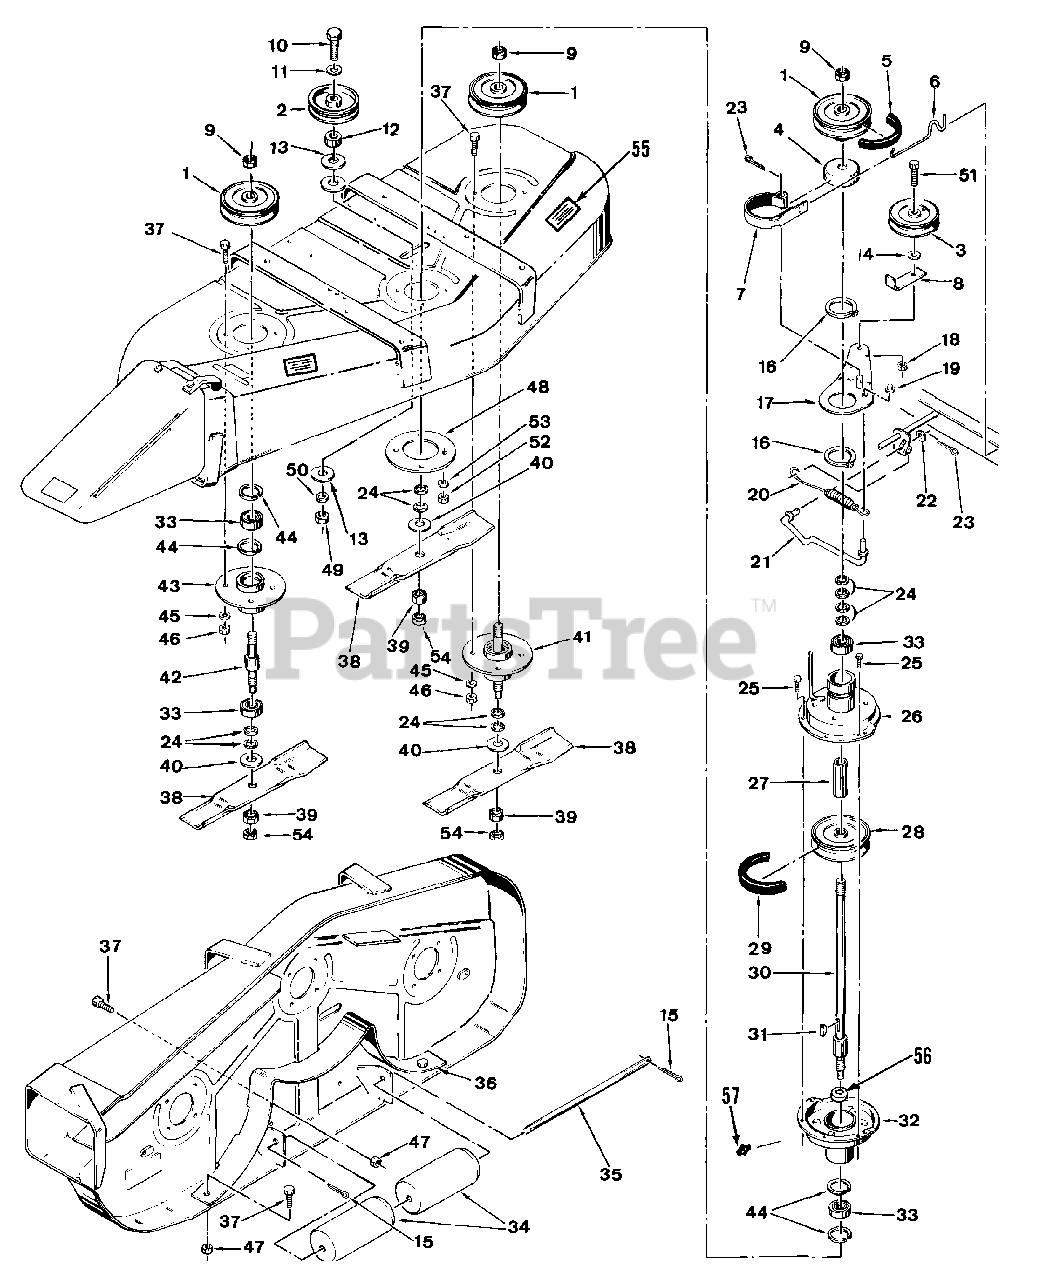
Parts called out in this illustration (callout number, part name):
1	Pulley
2	Pulley Deck Idler
3	Pulley - Idler
4	Brake Drum
5	Drive Belt
6	Brake Link
7	Brake Band
8	Belt Restrictor
9	NUT, 3/4-16 Hex Jam
10	5/8-11 x 21 Hex Hd. Mach. Bolt
11	Bolt Ferrule
12	Idler Ferrule
13	5/8 SAE Flat Washer
14	3/8 SAE Washer
15	Cotter Pin - 5/32 x 1
16	RING, 2" External Retaining
17	Idler Structure
18	3/8-24 Lock Nut
19	Push Nut
20	Spring
21	Control Rod
22	5/16 Flat Washer
23	Cotter Pin - 3/32 x 3/4
24	Washer
25	1/4-5/8 Self Topping Screw
26	Center Housing Structure
27	Top Ferrule
28	Pulley
29	Deck Belt
30	Center Shaft
31	Woodruff Key
32	Housing Structure
33	Bearing
35	Roller Shaft
36	Baffle
37	5/16-24 x 3/4 Hx Hd Capscrew
38	Blade
39	Shoulder Nut
41	Outside Spindle Assembly - in
42	Spindle
43	Housing Structure
44	Retaining Ring
45	5/16 Lock Washer
46	NUT, 5/16-24 Hex
47	5/16-24 Lock Nut
48	Flange
49	5/8-11 Hex Nut
50	5/8-11 Straight Lock Washer
51	3/8-24 x 1-3/4 Cap Screw
52	5/16-18 Hex Nut
53	5/16 Lock Washer
54	5/8-18 Hex Lock Nut
55	Long Foot Pad
57	1/4-28 Grease Fitting
